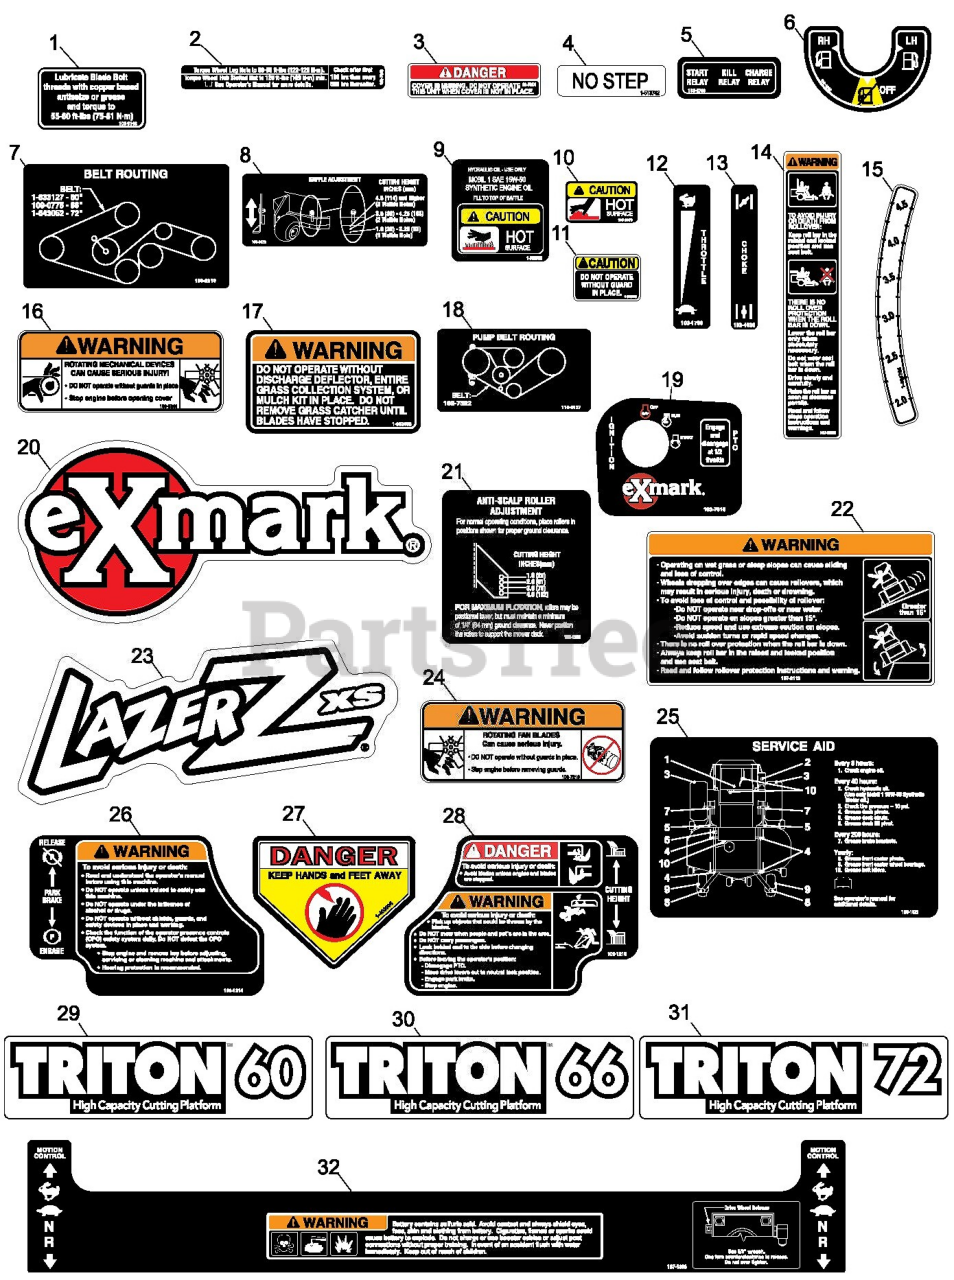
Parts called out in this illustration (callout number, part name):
1	DECAL,BOLT TORQUE
3	DECAL-COVER, MISSING
4	DECAL,NO STEP
5	DECAL,RELAY
6	DECAL-VALVE, FUEL
7	DECAL,BELT ROUTING
8	DECAL,BAFFLE ADJUSTMENT
10	DECAL-CAUTION
11	DECAL-GUARD
12	DECAL,THROTTLE ONLY
13	DECAL,CHOKE
14	DECAL-WARNING, FOLDING RO
15	DECAL-HEIGHT, DECK
16	DECAL-DEVICES, ROTATING
17	DECAL-WARNING, DISCHARGE
18	DECAL,HYDRO BELT ROUTING
20	DECAL,EXMARK
21	DECAL,ANTISCALP
22	DECAL-WARNING
23	DECAL,LAZER XS MODEL
24	DECAL,PUMP FAN WARNING
25	DECAL,SERVICE AID
26	DECAL,PARK BRAKE
27	DECAL-DANGER
28	DECAL,DECK HEIGHT
29	DECAL,TRITON 60
30	DECAL,TRITON 66
31	DECAL,TRITON 72
32	DECAL-CONSOLE, TOP
